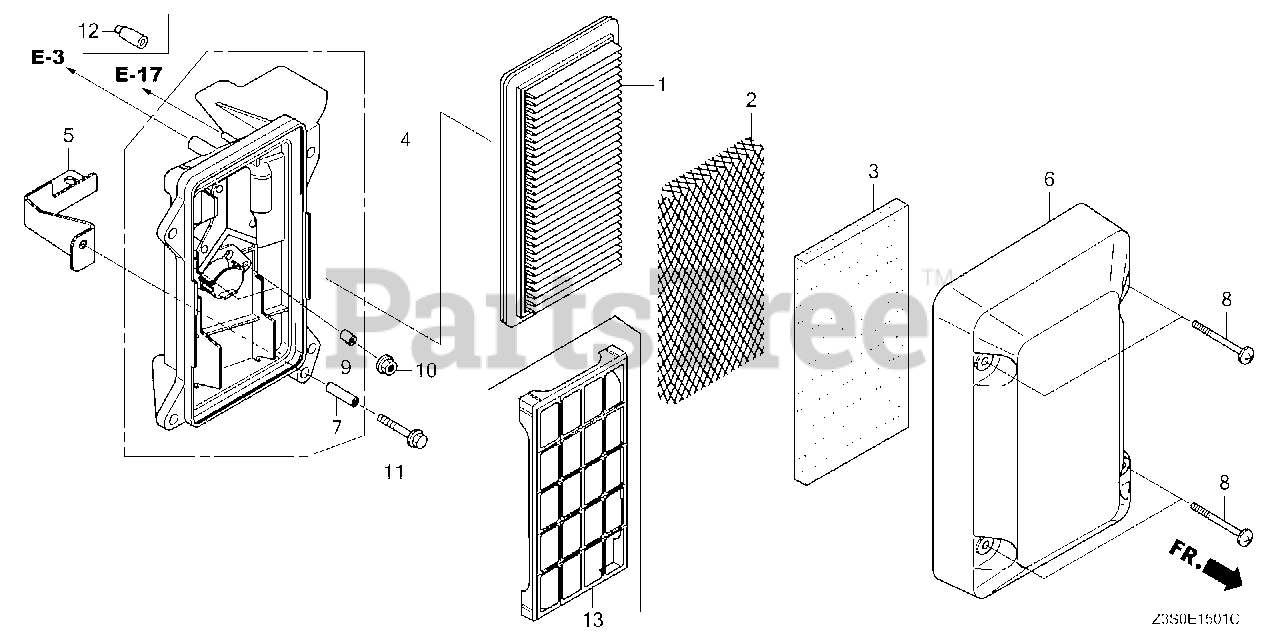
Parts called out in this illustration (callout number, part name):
1	ELEMENT, AIR CLEANER
2	GRID, AIR CLEANER
3	FILTER (OUTER)
4	HOUSING, AIR CLEANER
5	STAY, AIR CLEANER
6	COVER, AIR CLEANER
7	COLLAR, AIR CLEANER
8	BOLT, AIR CLEANER COVER
9	COLLAR (6MM)
10	NUT, FLANGE (6MM)
11	BOLT, FLANGE (6X35)
13	GRID, AIR CLEANER
